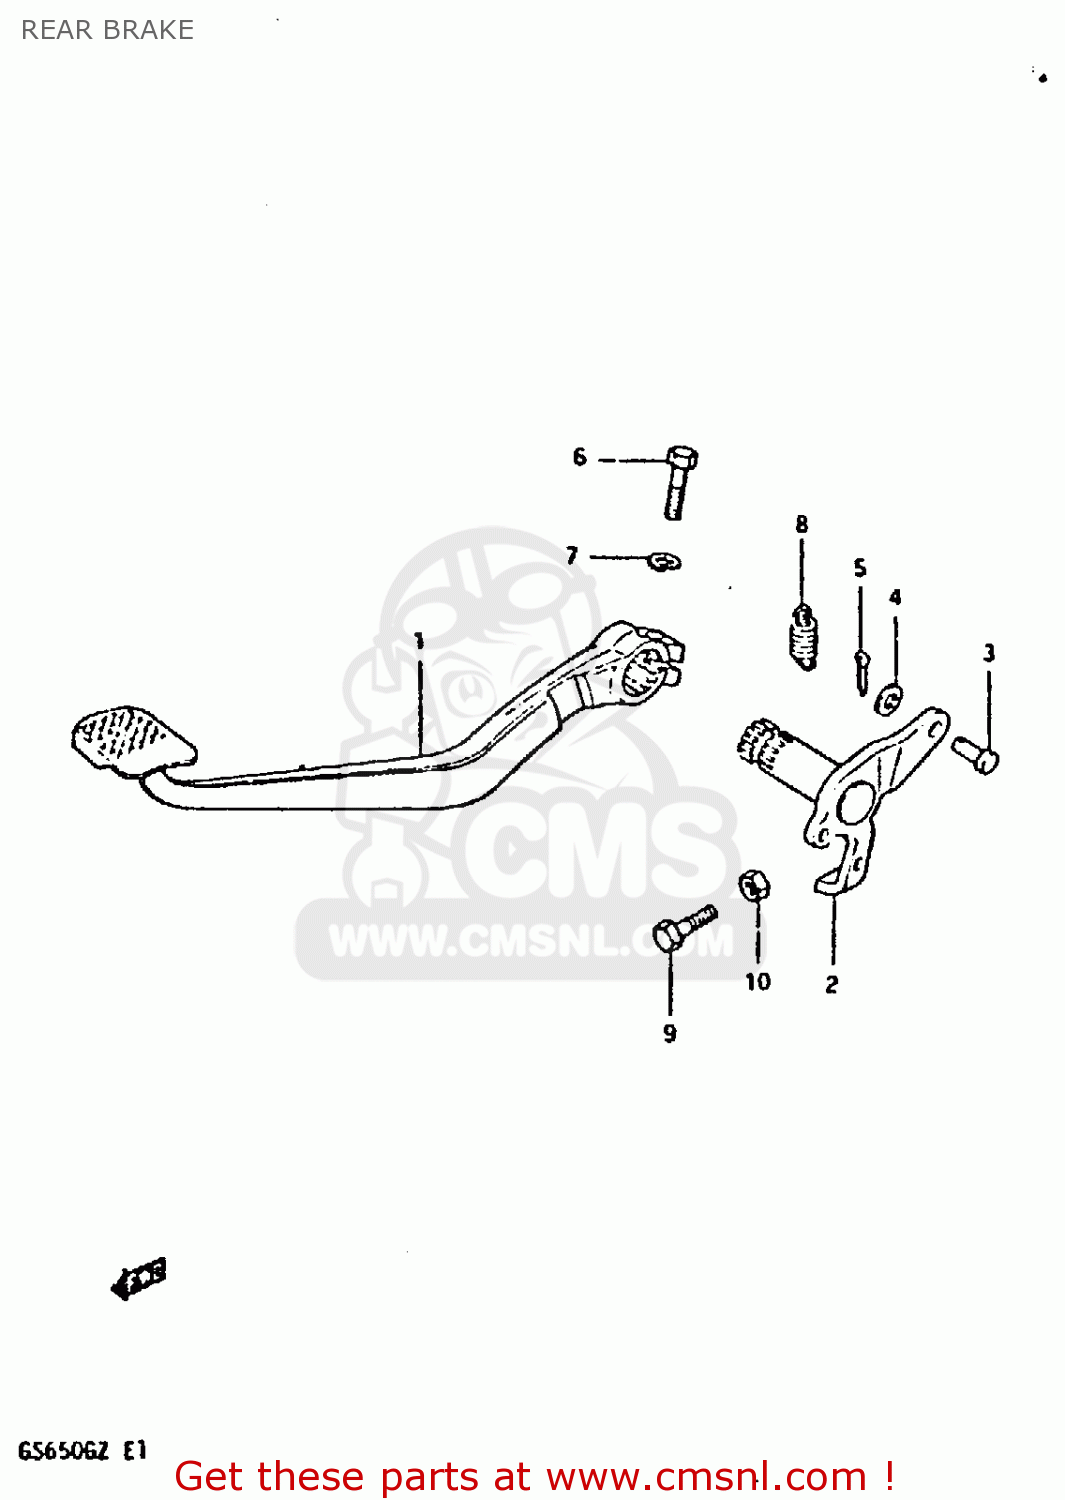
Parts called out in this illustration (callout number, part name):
1	PEDAL, BRAKE
2	ARM,BRAKE PEDAL ROD
3	PIN
4	WASHER
5	PIN
6	BOLT
7	LOCK WASHER
8	SPRING
9	BOLT
10	NUT
